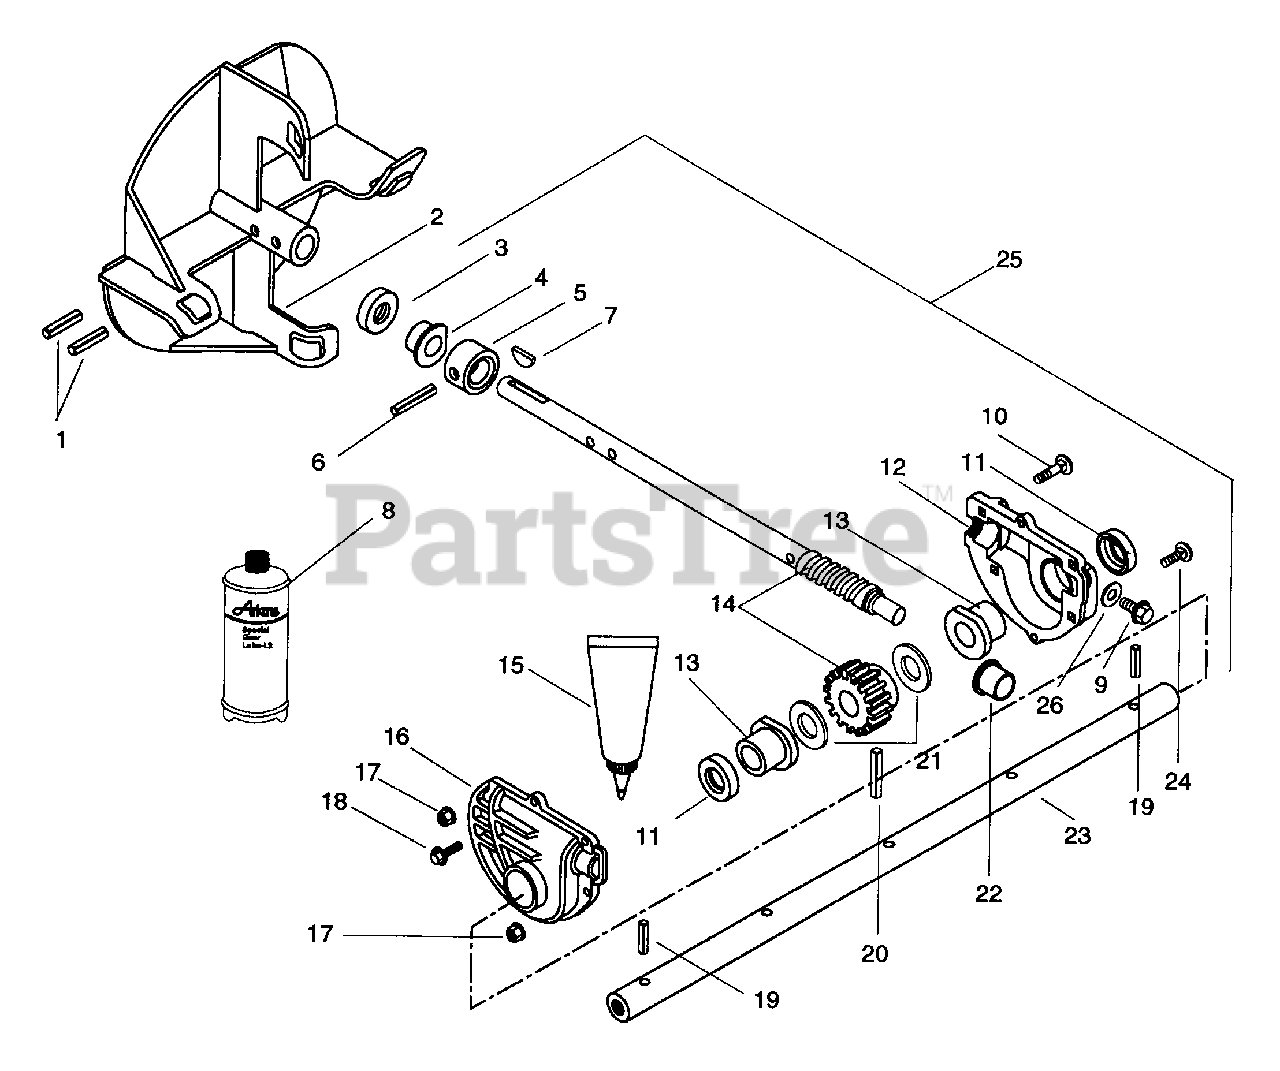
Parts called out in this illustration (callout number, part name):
1	PIN-ROLL .250X1.75
2	FAN - 12"
3	SEAL-OIL .750X1.375X.250
4	BSHG-FLG .750X1.000X.750X1.250
5	THRUST COLLAR
6	PIN-GRV .188X1.25 TP A
7	KEY-WDRF .188X.875X.375 SAE11
8	BOTTLE ONLY-S.SCREEN.FOR NO.80
9	SCR-TAP .375-16X .50 HWH PL TR
10	BLT-RDHDSQNK .25-20X1.25 GR5PL
11	SEAL-OIL 1.000X1.375X.250
12	CASE, GEAR-LH-LARGE BORE-ALUM.
13	BSHG-FLG 1.00X1.12
14	WORM SHAFT & GEAR ASSY
15	LOCTITE 518 GASKET--6ML TUBE
16	CASE, GEAR-RH-LARGE BORE-ALUM.
17	NUT-LK-FLG .250-20 PL
18	SCR-TAP 10-24X.75 HWH PL TR
19	PIN-ROLL .188X1.50
20	PIN-GRV .313X1.44 TP C
21	WSHR-HRD-THRS 1.007X1.542X.062
22	BSHG-FLG .502X1X.750
23	SHAFT, RAKE - 24"
24	BLT-RDHDSQNK .25-20X.88 PL
25	GEAR CASE-LRG BORE-ALUM.- 24"
26	WSHR-FIBER .437X.656X.032
